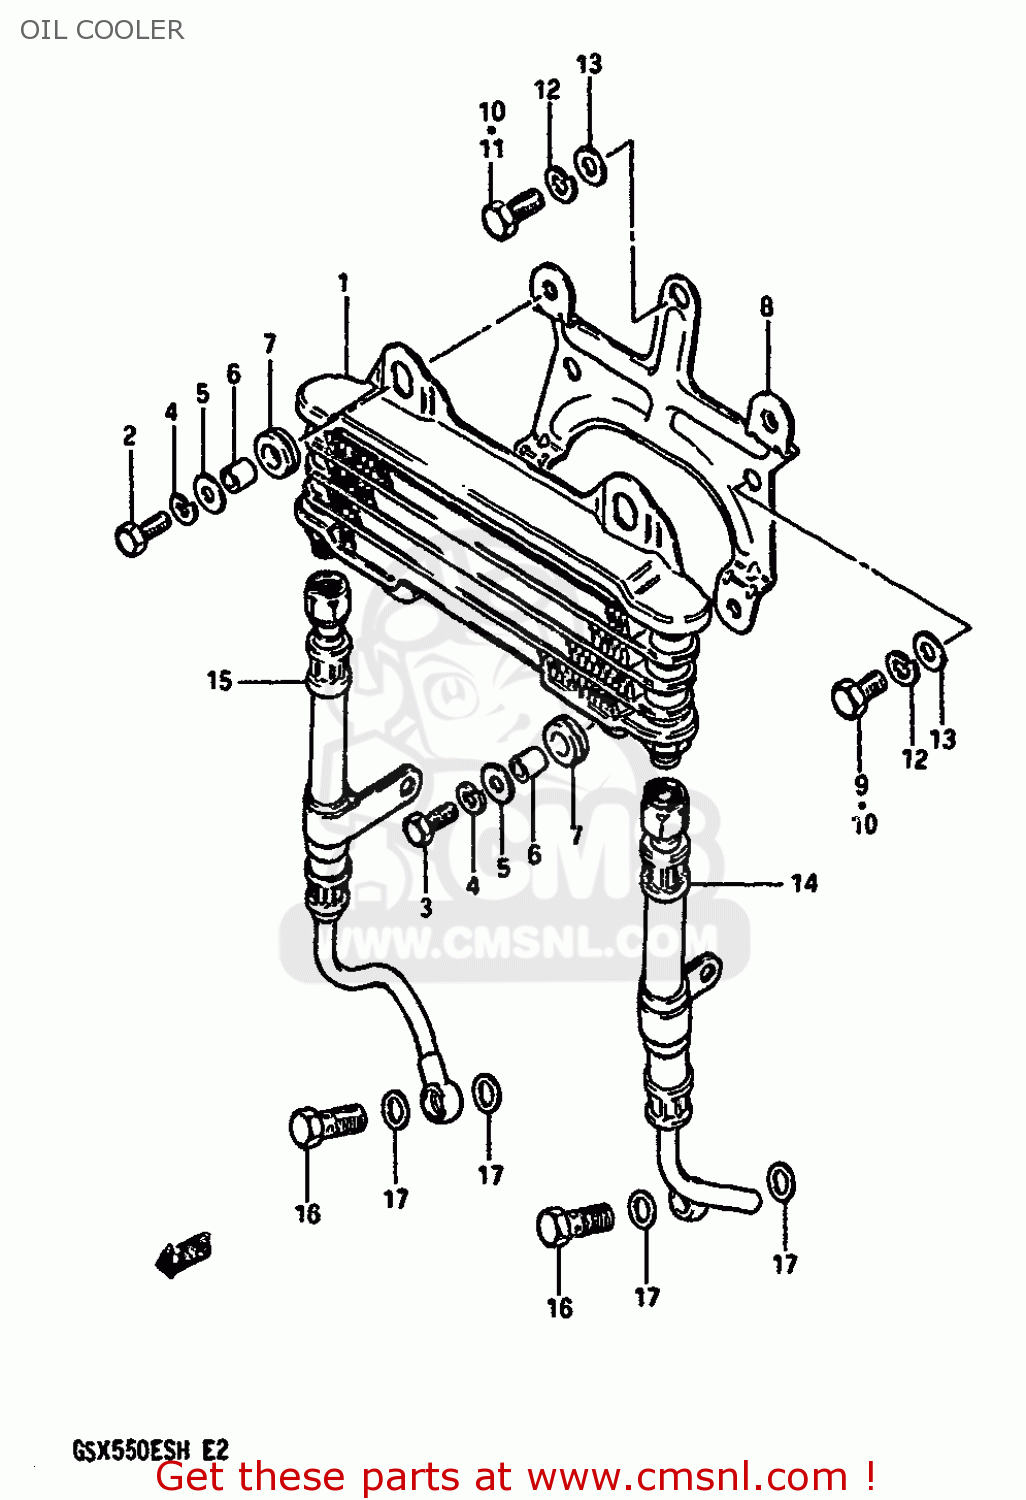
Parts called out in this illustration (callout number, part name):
1	COOLER ASSEMBLY,ENGINE OIL
2	BOLT
3	BOLT
4	WASHER,LOCK
5	WASHER (6.5X18X1.6)
6	SPACER (6.8X10X10)
7	CUSHION
8	BRACKET,OIL COOLER
9	BOLT
10	BOLT
11	BOLT
12	WASHER,LOCK,8.
13	WASHER
14	HOSE,ENGINE OIL,LEFT
15	HOSE,ENGINE OIL,RIGHT
16	BOLT UNION
17	GASKET(14X20X1.5) (NAS)
